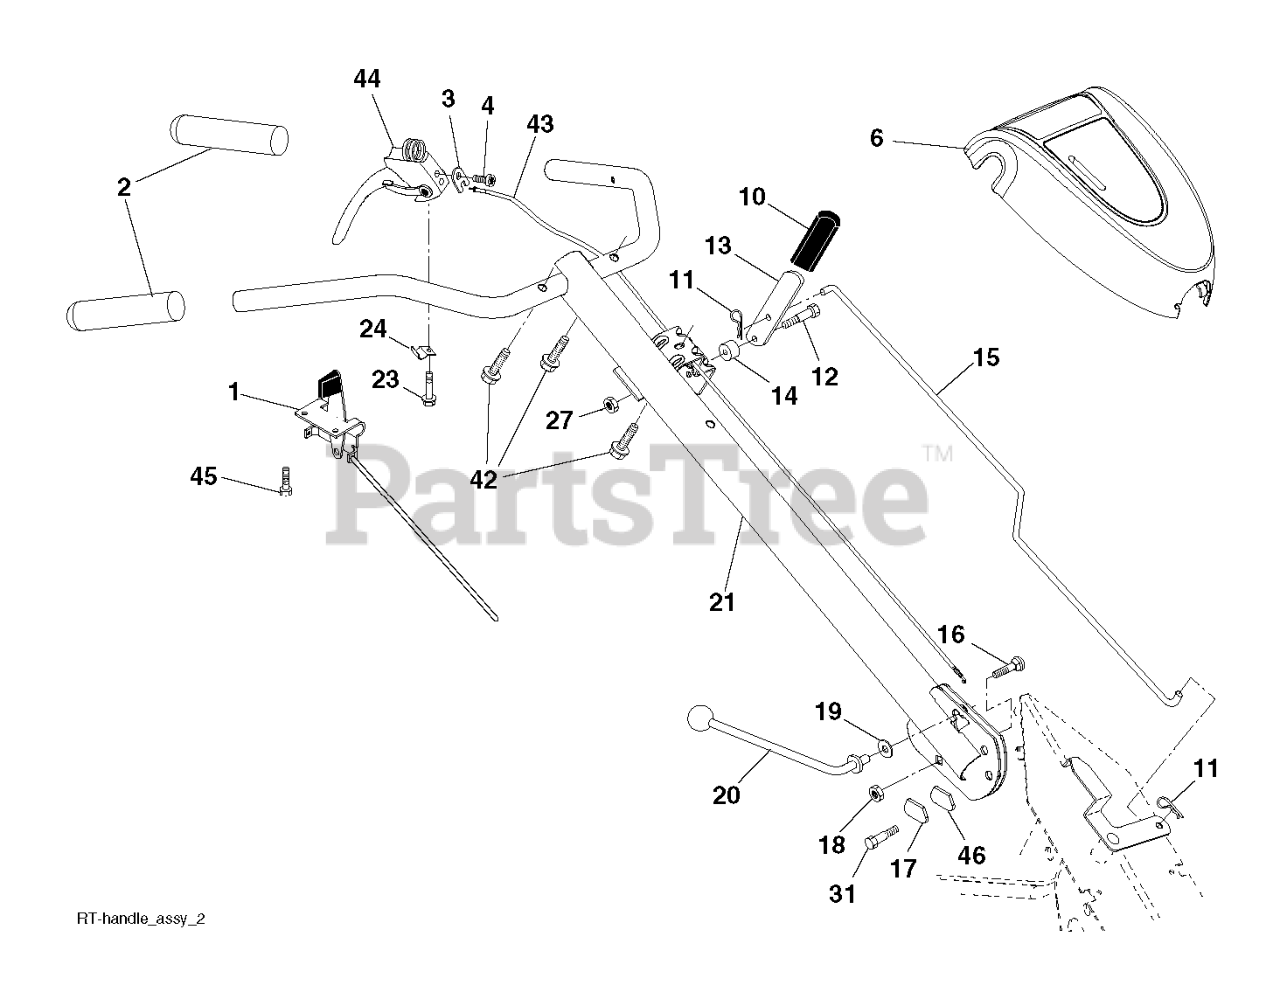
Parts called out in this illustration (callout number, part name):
1	CABLE ASSY THROTTLE 47" LENGTH
2	GRIP.1X5.06
3	CLIP.RETAINER.CABLE.BZP
4	SCREW.TORX.#10-14X1/2
6	CONSOLE.GREY.W/THROT.TR530
10	GRIP T
11	RETAINER M
12	SHOULDER BOLT ST
13	HANDLE.SHIFT.TILLER.498
14	GROMMET.RUBBER.CRT.TILLER
15	ROD SHIFT RT UNIVERSAL
16	BOLT D
17	LOCK.HANDLE.CRT
19	WASHER CRT
20	LEVER.LOCK.CRT
21	HANDLE.ASM.HUSQ/P.PRO.GREY
23	TAPPING SCREW
24	CLIP.PLATED
27	NUT T
31	BOLT.PIVOT
42	SCREW.#10 X 0.750.BOS
43	CABLE.HANDLE.TINE.CONT.CE
44	CONTROL.HANDLE.TWO.FUNCTION.CE
45	SCREW.#10 X 0.500
46	LOCK HANDLE
